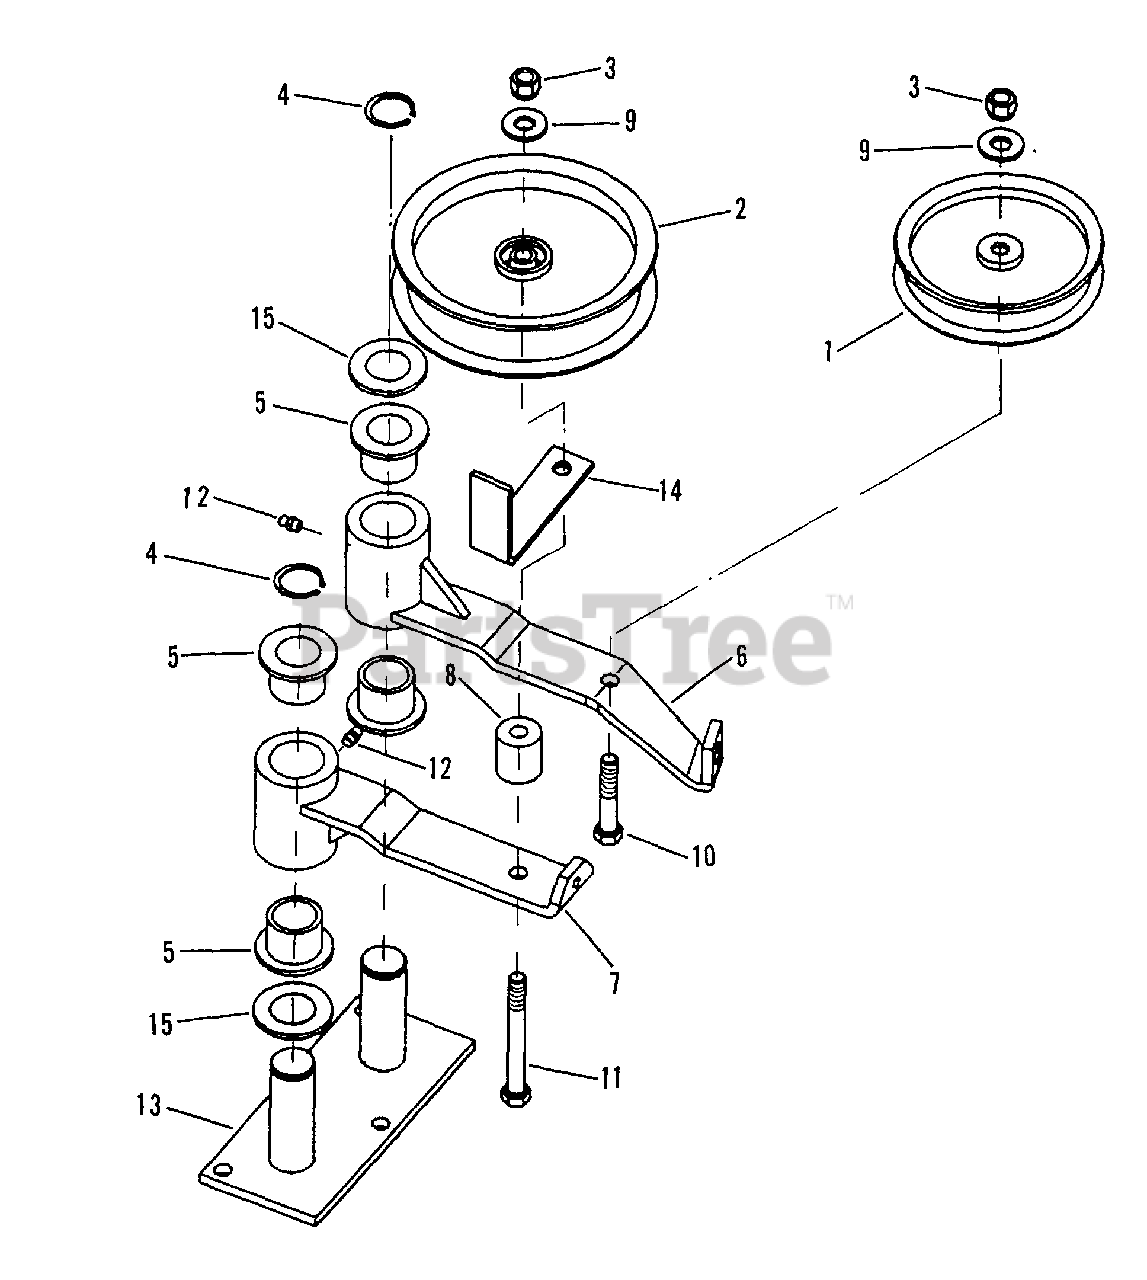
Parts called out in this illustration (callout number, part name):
1	PULLEY, Idler
2	PULLEY, Flat Idler 5" O.D.
3	NUT, 3/8-16 HEX NYLON LOCK
4	RING, 1" Retaining
5	BUSHING
6	IDLER ARM (Weldment)
7	IDLER ARM (Weldment)
8	SPACER, Idler Pulley
9	WASHER, 3/8" USS
10	BOLT, 3/8-16 X 2, GD5, CZ
11	BOLT, 3/8-16 x 3-1/4" Hex Head Cap, Grade 5
12	FITTING, Lube
13	PIVOT, Idler (Weldment)
14	BELT GUIDE
15	BUSHING
